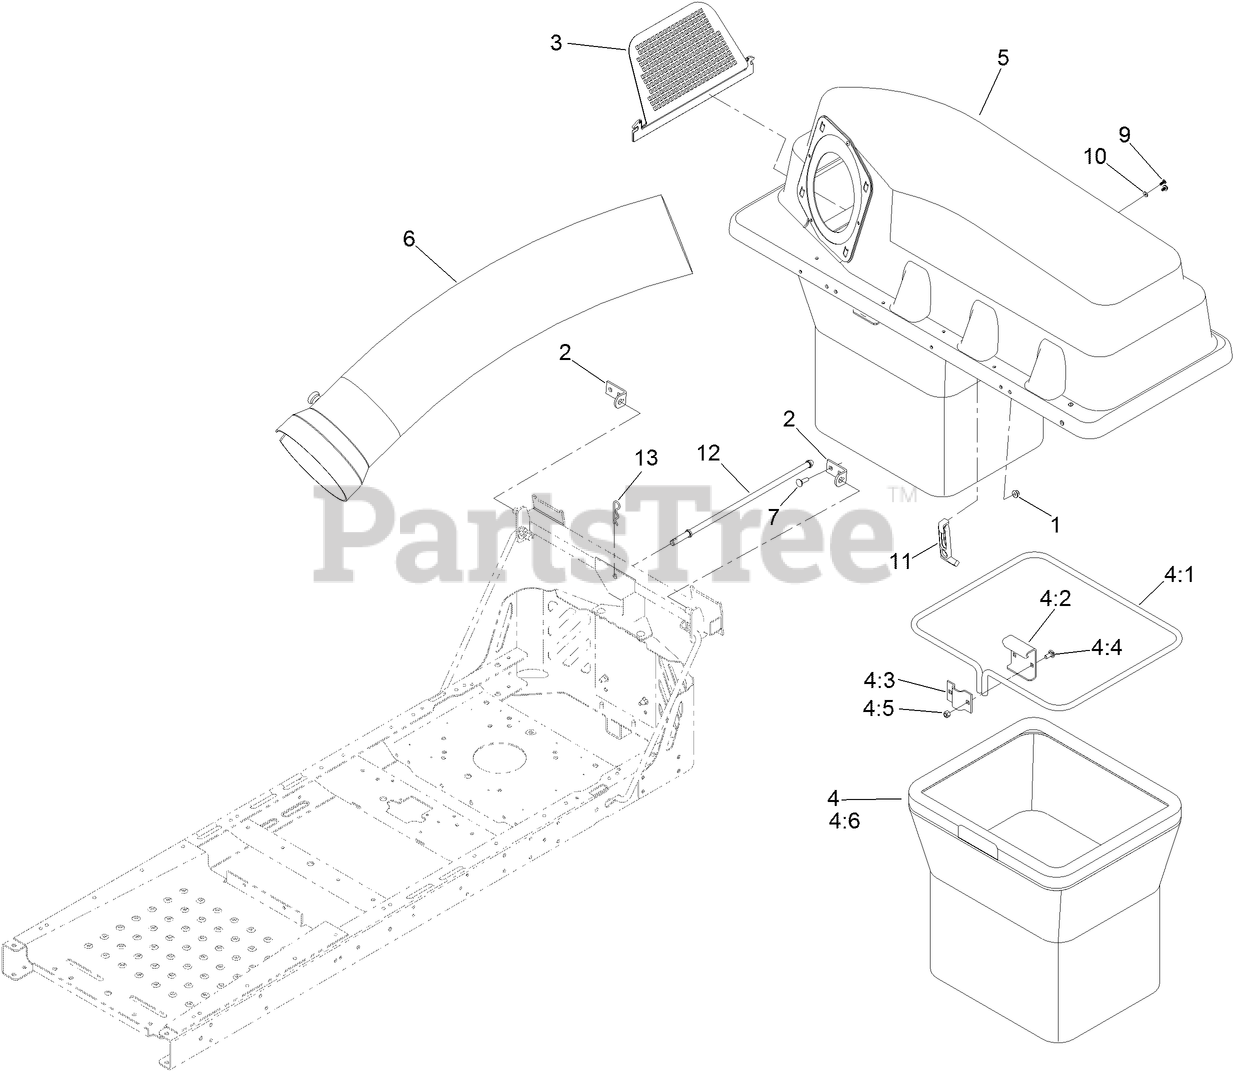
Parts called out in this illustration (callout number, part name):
1	NUT-HF, NI
2	BRACKET-PIVOT, HOPPER
3	SCREEN-BAGGER
4	BAG ASM
4:1	FRAME-BAG
4:2	HANGER-BAG
4:4	BOLT-CARR
4:5	NUT-LOCK, NI
4:6	BAG
5	BAGGER TOP ASM
6	TUBE-BAGGER
7	BOLT-CARR
9	SCREW-PLASTITE
10	WASHER-FLAT
11	LATCH-RUBBER
12	ROD-HOOD, DOWN (HOLD)
13	PIN-HAIR
